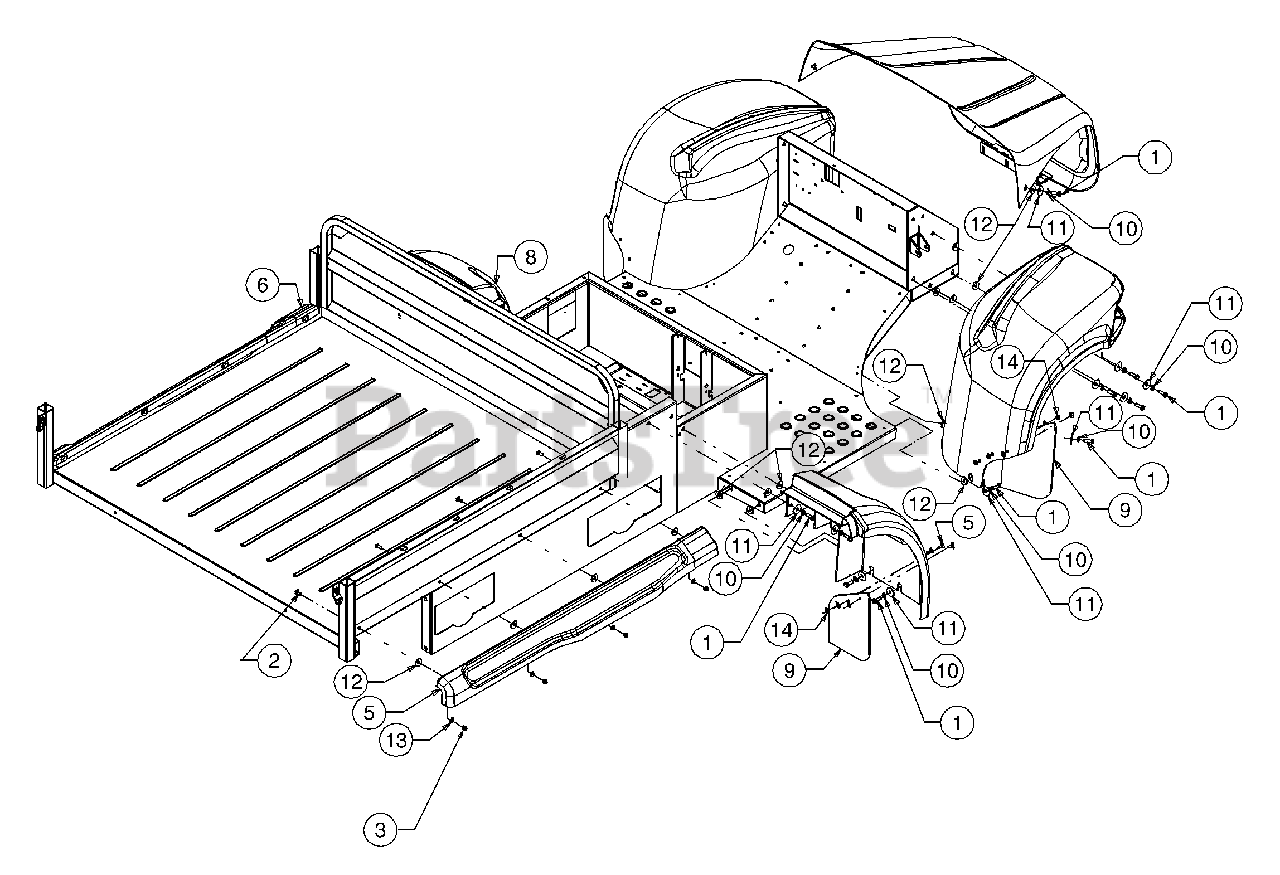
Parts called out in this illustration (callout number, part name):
1	Hex Screw, 5/16-18 x 1.00, Gr5
2	Hex Screw, 1/4-20 x .75
3	Hex Lock Nut, Nylon, 1/4-20
5	Panel, Bed Skirt, RH
6	Panel, Bed Skirt, LH
8	Panel, Rear Fender, LH
10	Lock Washer, 5/16
11	Flat Washer, .350 x 1.25 x .06
12	Washer, Rubber, .310 x 1.0 x .125
13	Flat Washer, .271 x .630 x .065
14	Flat Washer, .194 x .620 x .063
